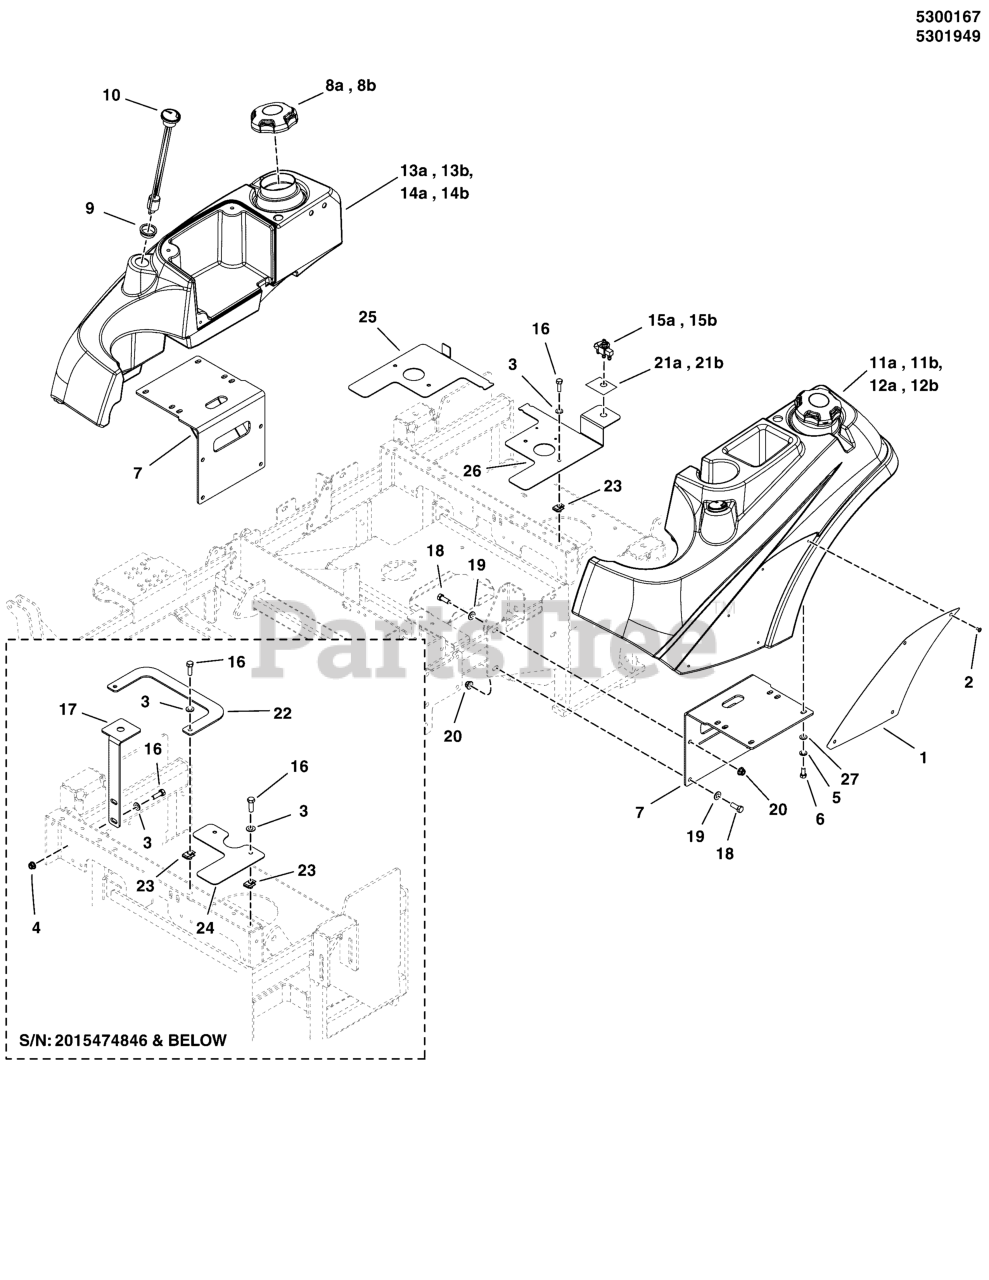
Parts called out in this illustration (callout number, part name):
1	PLATE, TANK BADGE - IS2000/COBALT - RED
2	SCREW, Allen Head, #10-24 x 3/8"
3	WASHER, 5/16" SAE
4	NUT, 5/16-18 HEX NYLOCK FLANGE
5	WASHER, 5/16 LOCK CZ
6	BOLT, 5/16-18 X 3/4 GD5
7	WELD, TANK MOUNT - BLK
9	GROMMET, FUEL GAGE
10	GAUGE, FUEL, 12
16	BOLT, 5/16-18 X 1" GRD5 YZ
17	FUEL, VALVE BRACKET - BLK
18	BOLT, 3/8-16 X 1" GD5 CZ
19	WASHER, 3/8 SAE
20	NUT, 3/8-16 HEX NYLOCK FLANGE
22	PLATE, FUEL HOSE SUPPORT - RED
23	BODY CLIP, 5/16-18-7GA MATERIAL
24	PLATE, FAN GUARD, IS3100
25	PLATE, FAN GUARD, FUSE - BLK
26	PLATE, FAN GUARD, FUEL - BLK
27	WASHER, 5/16 F436 FLAT
